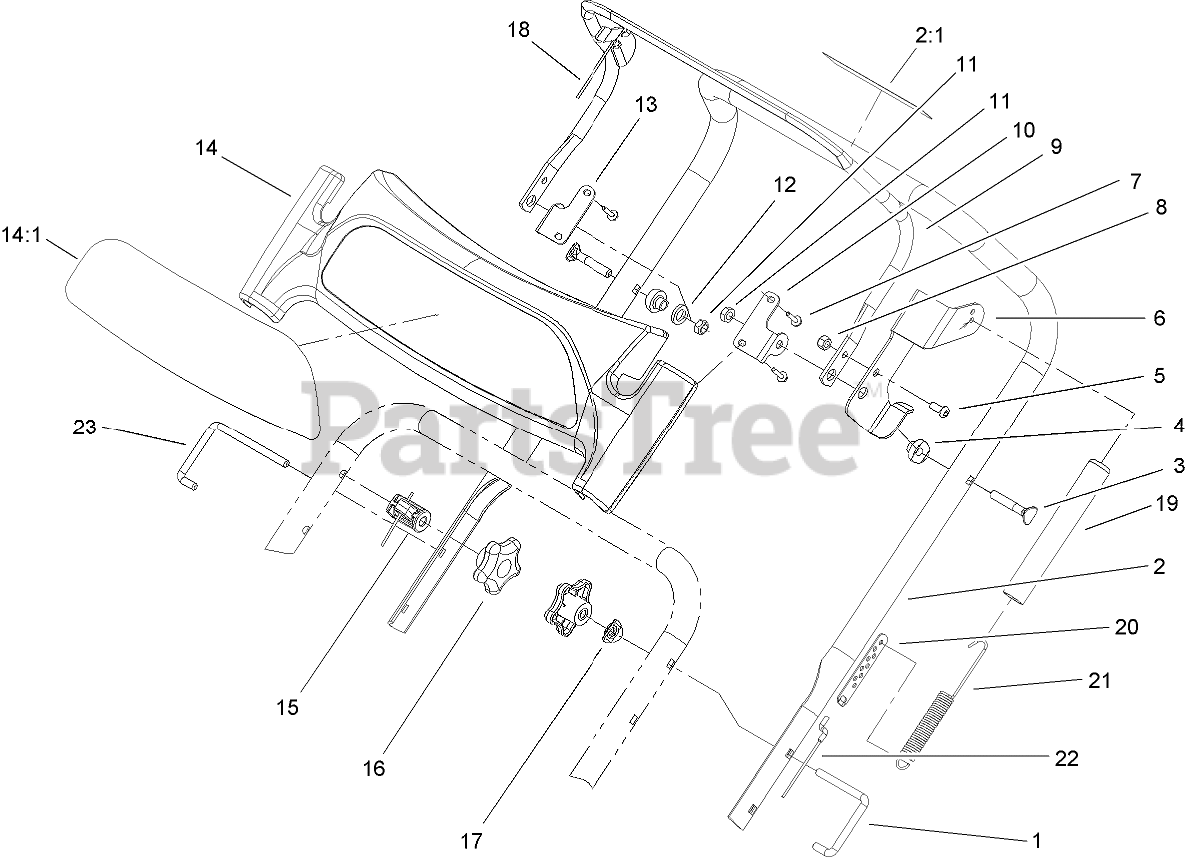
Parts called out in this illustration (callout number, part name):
1	LOCK-HANDLE
2	HANDLE-UPPER W/DECAL
2:1	DECAL-DRIVE, ROTOR
3	SCREW-HANDLE
4	SPACER-BAR, CONTROL
5	SCREW-HSBH
6	ARM-CLUTCH, HANDLE
7	SCREW-HWH
8	NUT-LOCK, NI
9	BAR-CONTROL
10	BRACKET-PANEL, LH
11	NUT-LOCK, NI
12	WASHER
13	BRACKET-PANEL, RH
14	DISPLAY HANDLE PANEL ASM
14:1	Decal-Display, Handle
15	GUIDE-Cable, PIVOT
16	KNOB-HANDLE
17	WASHER
18	CABLE-PIVOT
19	COVER-SPRING
20	ADJUSTER-CABLE, CLUTCH
21	SPRING-CABLE
22	CABLE-CLUTCH
23	LOCK-HANDLE, RH
